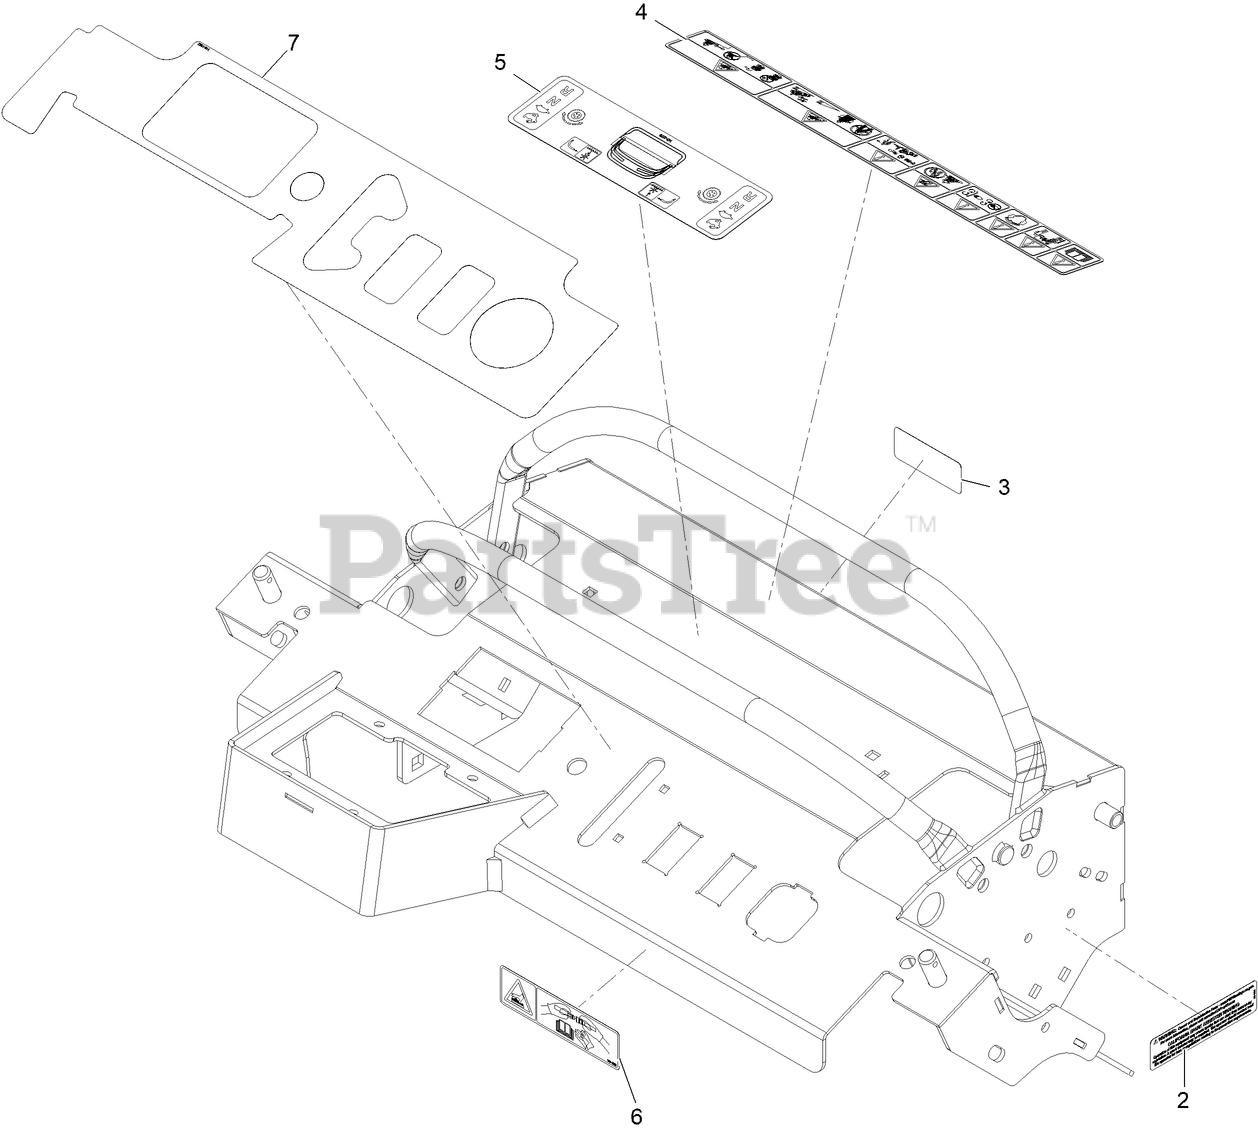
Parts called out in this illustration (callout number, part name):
2	DECAL-ARRESTOR, SPARK
3	DECAL - FUSE
4	DECAL-WARNING
5	DECAL-CONTROLS
6	DECAL-CAUTION
7	DECAL-CONTROL PANEL
